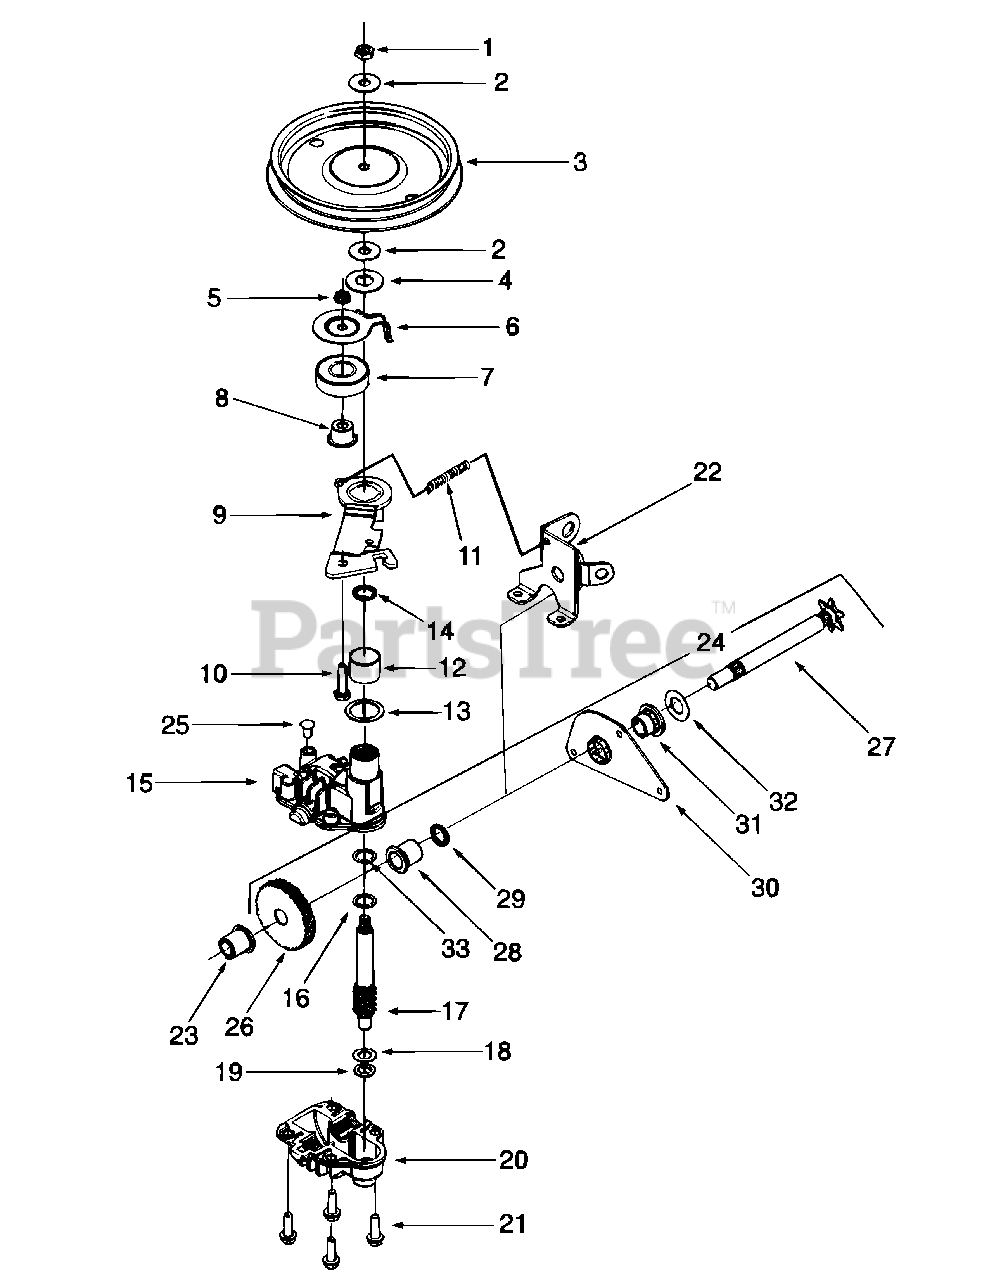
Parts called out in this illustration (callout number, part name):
1	Hex Jam Nut 5/16-24
2	Cupped Washer .325 ID x .930 OD x .04
4	Fl. Washer .510 x 1.120 x .060
5	Hex Ins Jam L-Nut 1/4-28
7	Ball Bearing 17 x 40 x 12 mm
8	Flange Spacer
9	Idler Bracket Ass’y
10	Hex Bolt 1/4-28 x 1" Lg
11	Extension Spring 0.33 OD x 1.25
12	Bearing Sleeve
13	Fl. Washer .885 x 1.145 x .030
14	Oil Seal
15	Upper Housing Ass’y
16	Thrust Washer .510 ID x .750 OD x .033
17	Pinion Shaft 10 T
18	Thrust Washer .382 ID x .70 OD
19	Thrust Washer .388 x .625 x .062
20	Lower Housing Ass’y
21	Thd Forming Scr. 1/4-20 x .75
24	Shaft Ass’y
27	Output Shaft 6 T
28	Flange Bearing
30	Pivot Bracket
31	Flange Bearing .506 ID
32	Washer, Flat .505 ID x 1.0
33	Thrust Bearing .507 ID x .750 OD x .0625
